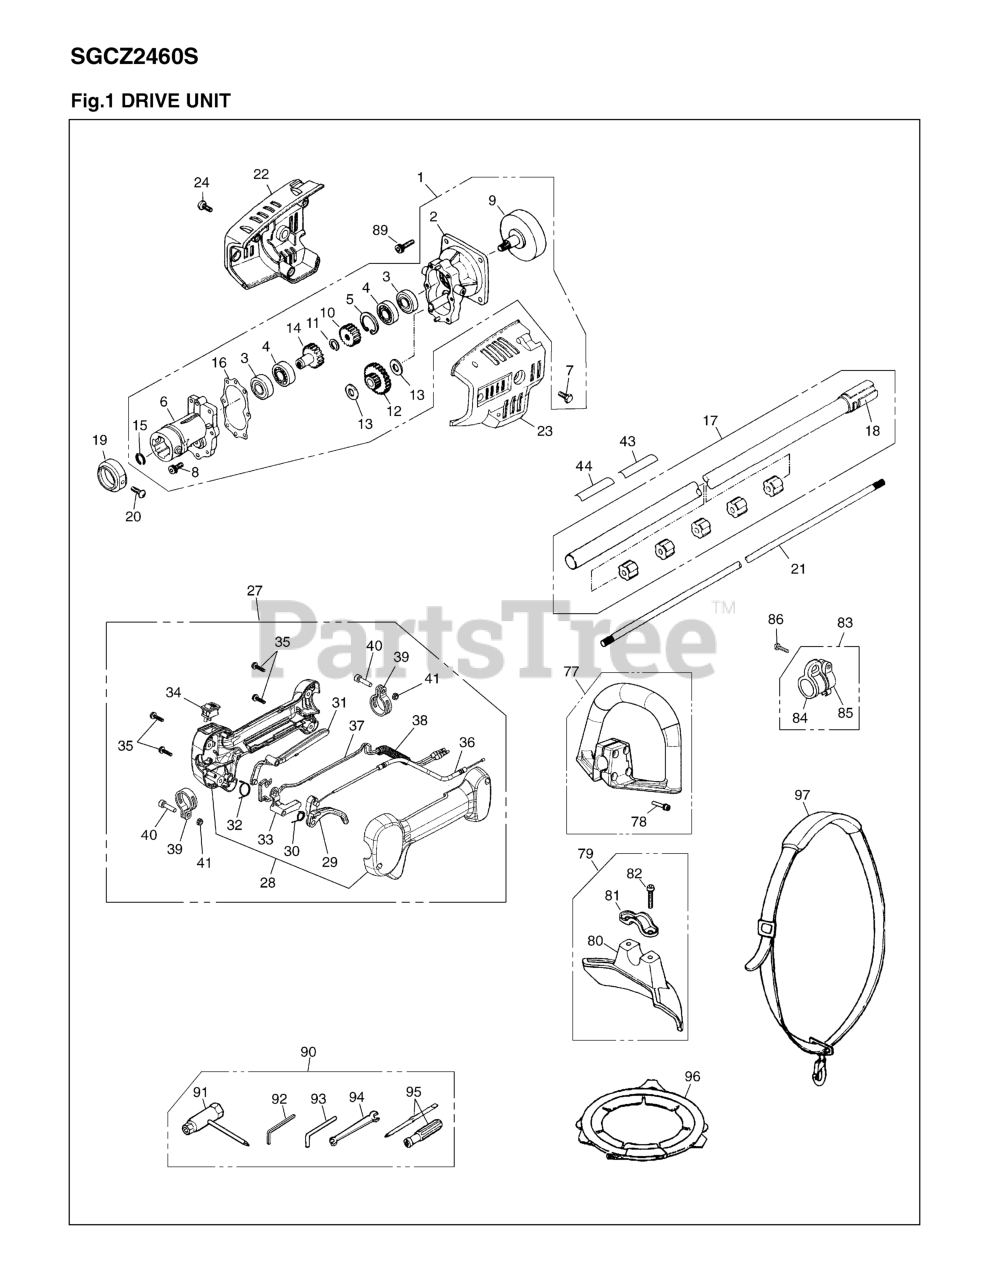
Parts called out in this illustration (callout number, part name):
1	MISSION ASSEMBLY
2	CASE,REAR COMP(R
6	CASE, FRONT
7	BOLT, M6 x 8
8	BOLT, M5 x 20
9	DRUM
10	GEAR, PINION
11	RING, SNAP
12	GEAR (RPLS 38051
13	WASHER
14	GEAR, WHEEL
16	GASKET (RPLS 380
17	PIPE COMP (RPLS
18	CUSHION (RPLS 38
19	CAP
20	SCREW, M5 x 10
21	SHAFT
22	COVER,RIGHT(RPLS
23	COVER, LEFT(RPLS
24	SCREW
27	GRIP ASSY
28	GRIP, HALF SET
29	LEVER, THROTTLE
30	SPRING, THROTTLE
31	LEVER FOR GRIP (
33	LEVER JOINT
36	CABLE COMP
37	CORD COMP
38	TUBE
40	BOLT (RPLS 28501
41	NUT
43	NAME PLATE
44	LABEL CAUTON FOR
77	HANDLE ASSY. (RP
79	GUARD ASSY (RPLS
80	GUARD (RPLS 3565
81	CLAMP (RPLS 5807
82	BOLT, M6 x 1.30
83	HANGER COMP.
84	HANGER
89	BOLT, M6 x 20
90	TOOL SET
93	WRENCH (TOOL)
94	SPANNER,8 x 10(R
95	SCREWDRIVER
96	COVER
97	STRAP ASSY
